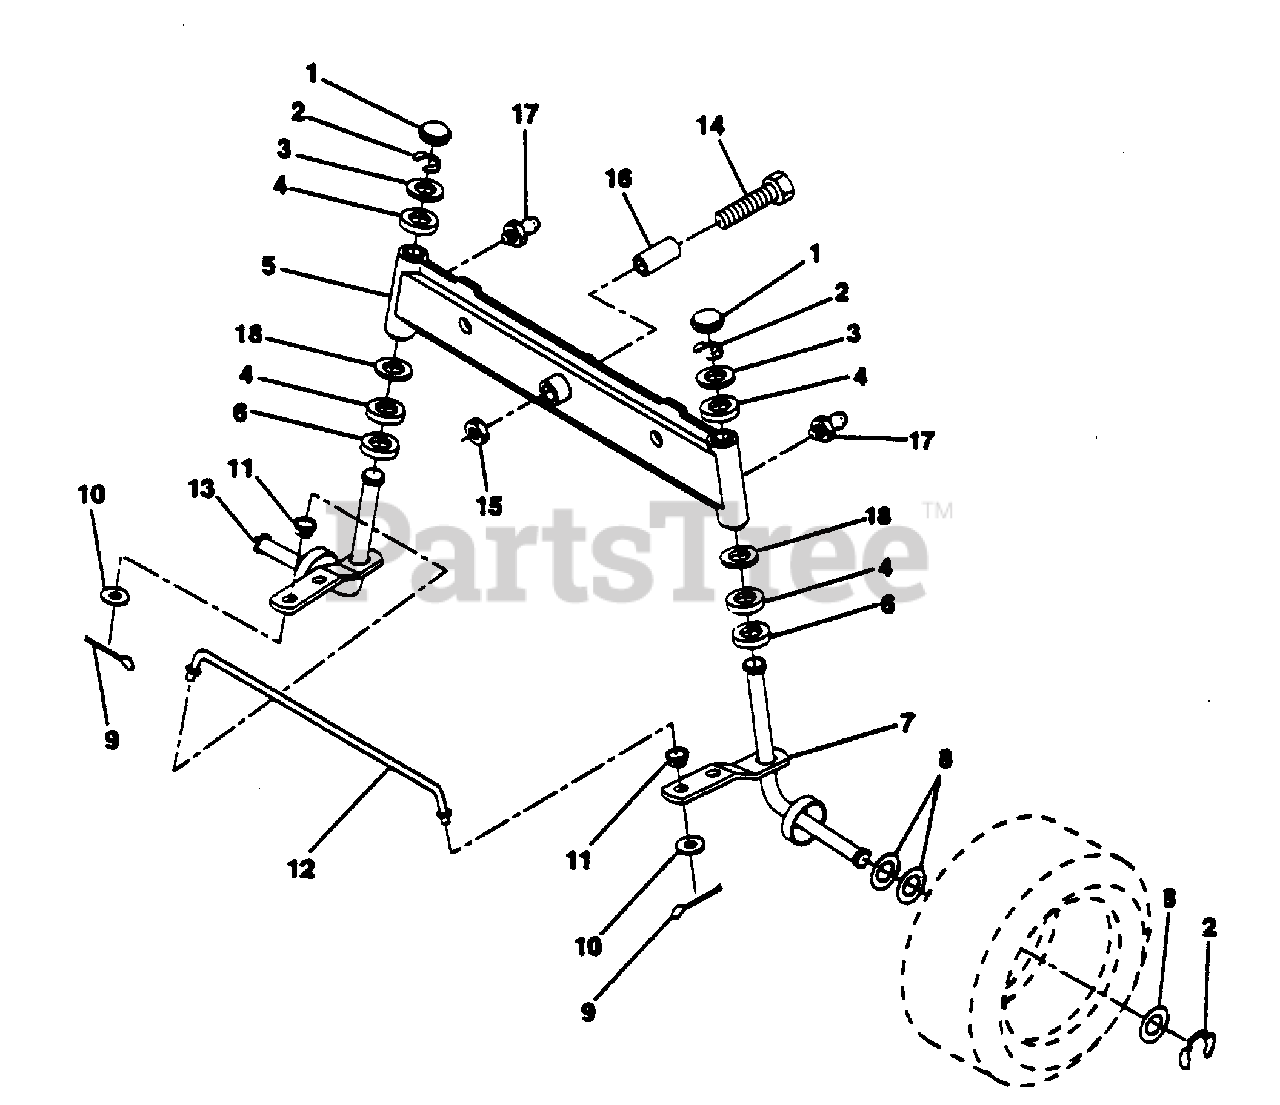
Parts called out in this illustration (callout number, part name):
1	Cap, Spindle (AYP part number)
2	Ring, Clip (AYP part number)
3	Washer 25/32 x 1-5/8 x 16 Ga. (AYP part number)
4	Nyliner (AYP part number)
5	Axle, Front (AYP part number)
6	Bearing, Thrust (AYP part number)
7	Spindle, R.H. Asm.
8	Washer 25/32 x 1-1/4 x 16 Ga. (AYP part number)
9	Pin, Cotter 1/8 x 3/4 (AYP part number)
10	Washer 13/32 x 13/16 x 16 Ga. (AYP part number)
11	Bushing (AYP part number)
12	Rod, Tie (AYP part number)
13	Spindle, L.H. Asm. (AYP part number)
14	Bolt Hex 5/1-11 x 3-1/2 (AYP part number)
15	Nut, Lock Flange 5/8-11 (AYP part number)
16	Spacer, Bearing Axle (AYP part number)
17	Fitting, Grease (AYP part number)
18	Washer 27/32 x 1-1/4 x 16 Ga. (AYP part number)
